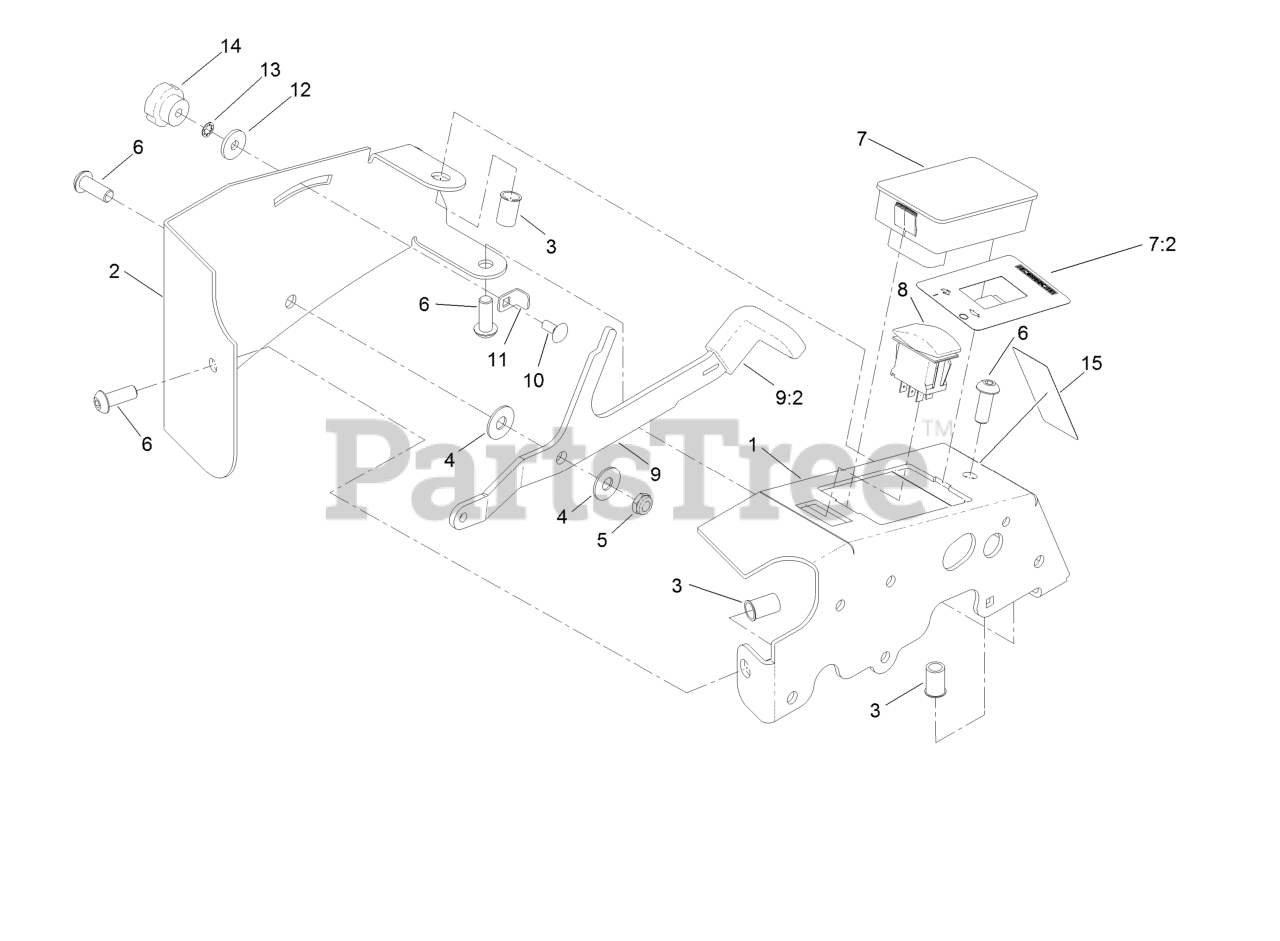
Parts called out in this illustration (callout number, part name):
1	Bracket-Mount
2	Cover-Controller, Spreader
3	Insert-Nut
5	Nut-Lock, NI
6	Screw-HSBH
7	Spreader Control Module ASM
7:2	Decal-Speed, Impeller
8	Switch, (On)-Off-(On)
9:2	Grip-Control, Lever
10	Screw-CARR
11	Bracket-Gate, Set
12	Washer-Friction
13	Washer-Lock, Int
14	Knob-Chute
15	Decal-Control, Spread
